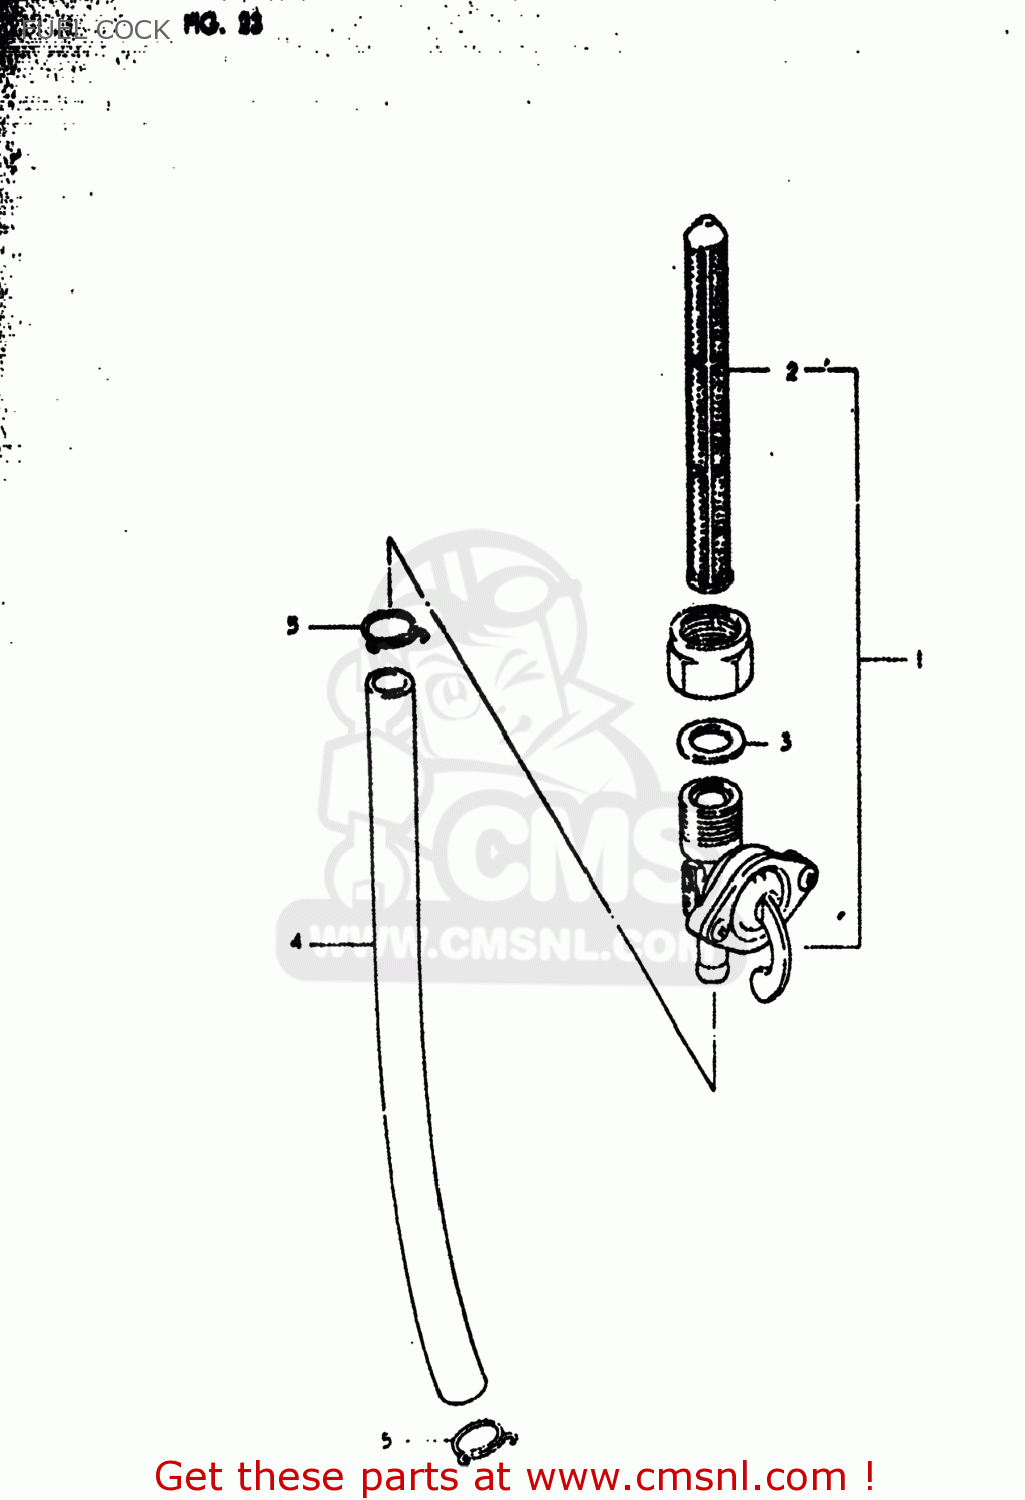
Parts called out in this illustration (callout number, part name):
1	COCK ASSY,FUEL
2	FILTER,FUEL
3	GASKET,FUEL COCK (NAS)
4	HOSE
5	CLIP
